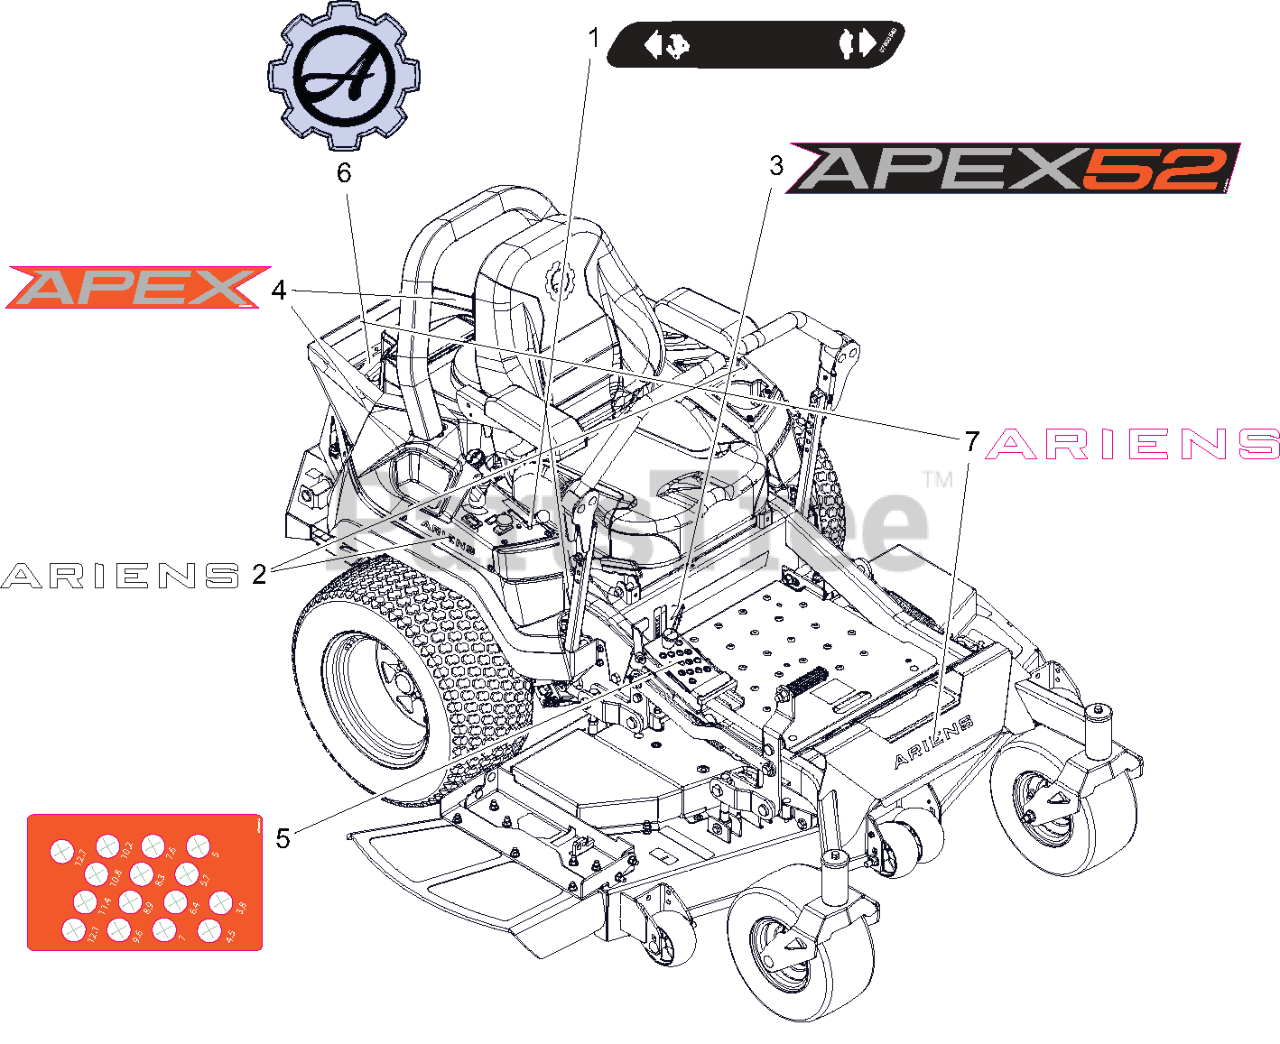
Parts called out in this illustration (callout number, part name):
1	DECAL, DASH DECAL
2	DECAL, ARIENS (6.50")
3	DECAL, 52" APEX KICKPLATE
4	DECAL, APEX FENDER
5	DECAL, APEX HOC METRIC
6	DECAL- ARIENS GEAR BADGE
7	DECAL - ARIENS 9.625"
